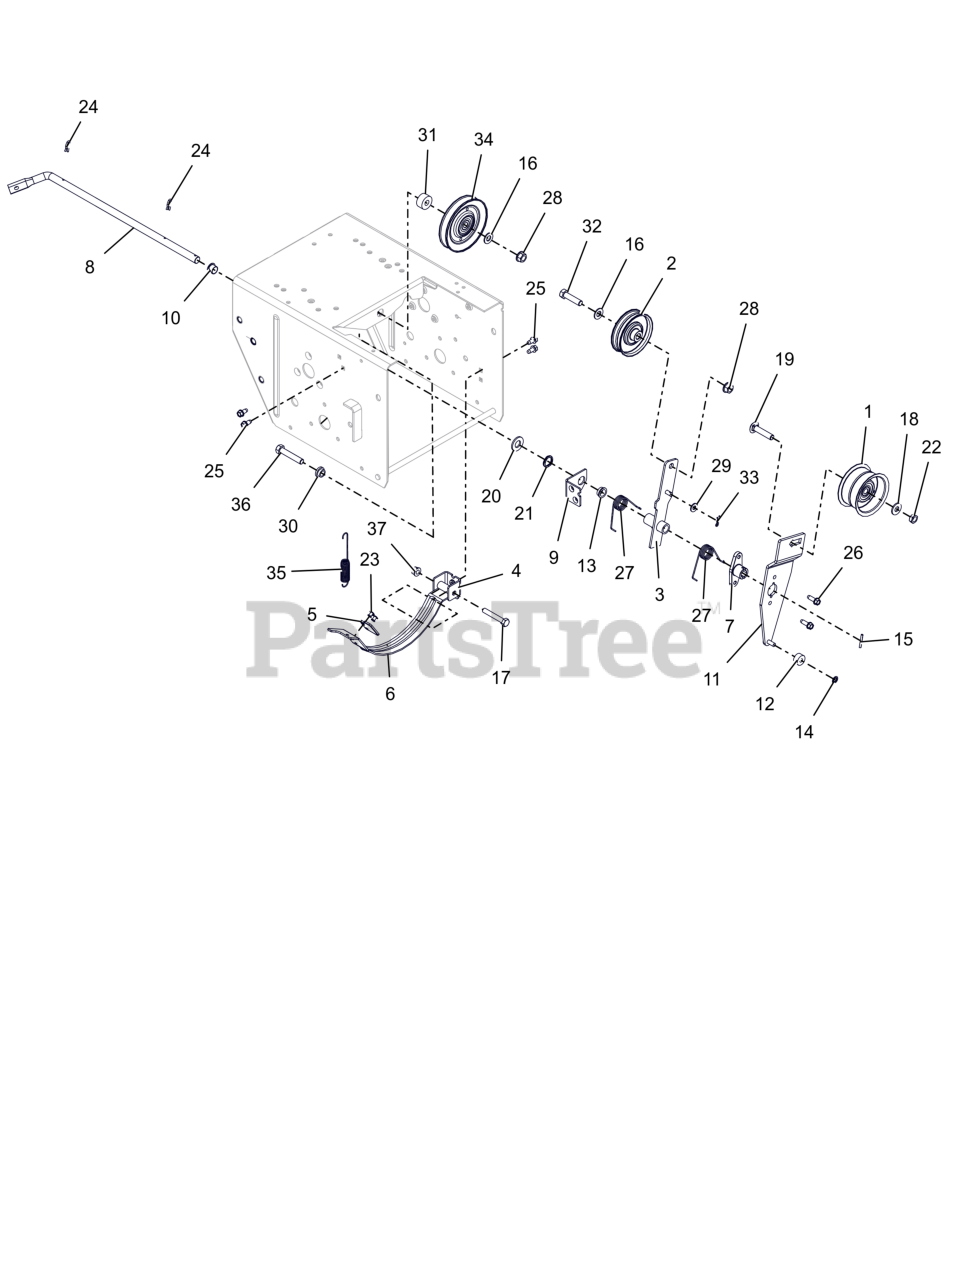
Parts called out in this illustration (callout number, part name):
1	IDLER, FLANGE -2.75 OD X .375 ID
2	IDLER, FLAT - 3.000" X .750"
3	ARM, TRACTION CLUTCH
4	PIVOT, BRAKE
5	PAD, BRAKE
6	ARM, BRAKE-ATTACHMENT
7	HUB, BRAKE ARM
8	ARM, ATTACHMENT
9	BRACKET, SUPPORT
10	BUSHING, POLYLINER-.50 SPLIT
11	ARM, IDLER - ATTACHMENT
12	BSHG,SLV .265 X .625 X .375
13	BSHG,FLANGE .500X.625X.270X.75
14	RG-RTNG-EXT .250X.010
15	PIN-ROLL .125X1.00
16	WSHR,FLT .406X.812X.065 ZCC
17	BLT, HEX .31-18X2.00 G5 ZCC
18	WSHR,FLT .375X.875X.083 ZCC
19	BLT, RHSSN .38-16X1.75 G5 ZCC
20	WSHR,FLT .531X1.062X.095 ZCC
21	WAVE SPRING .600X.875X.25FH
22	NUT-LK-CTR-JAM .375-16 GB ZCC
23	RVT, POP .1875 ZCC
24	CLIP, SPRING
25	SCR-TAP .25-20X.50 HWH ZCC
26	SCR,TAP .25-20X.75 HWH TR ZCC
27	SG-TORS .067X.88
28	NUT-LK-TOP-FLG .38-16 ZC120
29	WSHR,FLT .281X.625X.065 ZCC
30	BSHG, FLANGE .391X.56X.313X.75
31	BSHG,POCKET .391X.570X1.0X.450
32	BLT, HEX .38-16X1.50 G5 ZCC
33	PIN, HAIR #178 .06X.77 ZCC
34	SHV, .38"ID X 4.00"OD V-IDLER
35	SG-TENS .056X.60X4.40
36	BLT,HEX .38-16X2.00 G5 ZCC
37	NUT-LK-TOP-FLG .312-18 GF ZCC
